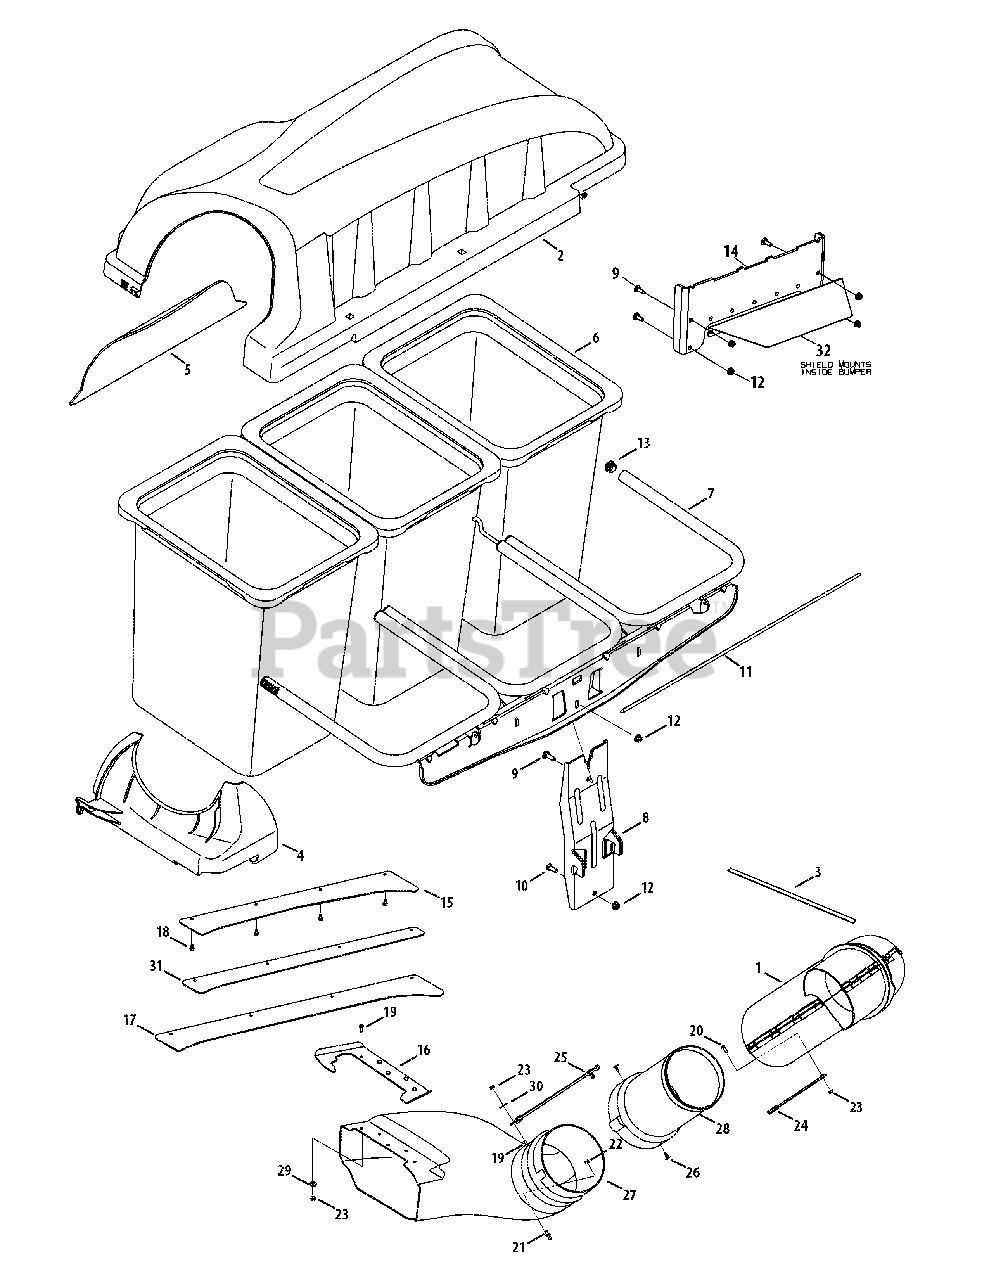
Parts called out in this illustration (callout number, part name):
1	Chute Assembly, Bagger, Upper, 32in
2	Cover Assembly, Bagger, Triple
3	Foam, Tape, .75 Wide X .125 Thick
4	Support, Bagger, Upper Chute
5	Screen, Bagger
6	Bag Assembly, Grassbag, Cub
7	Support Assembly, Bag, Triple
8	Bracket Assembly, Bagger, Vert. Support
9	Screw, Carriage, 5/16-18, 1.00
10	Hex Head Screw, 5/16-18, .75, Gr5, Std
11	Pin, Cover Hinge, Bagger, Triple
12	Nut, Flange Lock, 5/16-18, Grf, Nylon
14	Bracket, Bagger
18	Screw, Tap, 1/4-20, 0.500, Hxindwsh
19	Hex Head Screw, 1/4-20, .620, Gr5, Std
20	Screw, Mach, 1/4-20, 0.750
21	Pin, Grasscatcher, 1/4-20
22	Nut, Hex Lock, 1/4-20, Gr8, Nylon
23	Nut, Flange Lock, 1/4-20, Grf
24	Strap, Chute, 11.65 Lg
25	Strap, Chute
26	Clip, Ratchet, .250 Dia
27	Chute, Elbow
28	Chute, Bagger, Adapter, 8x13.5
29	Wash, Bell, .265 X.75 X .062
30	Wash, Flat, .265x1.0x.030, Ht
31	Baffle, Front 54
32	Muffler Shield
